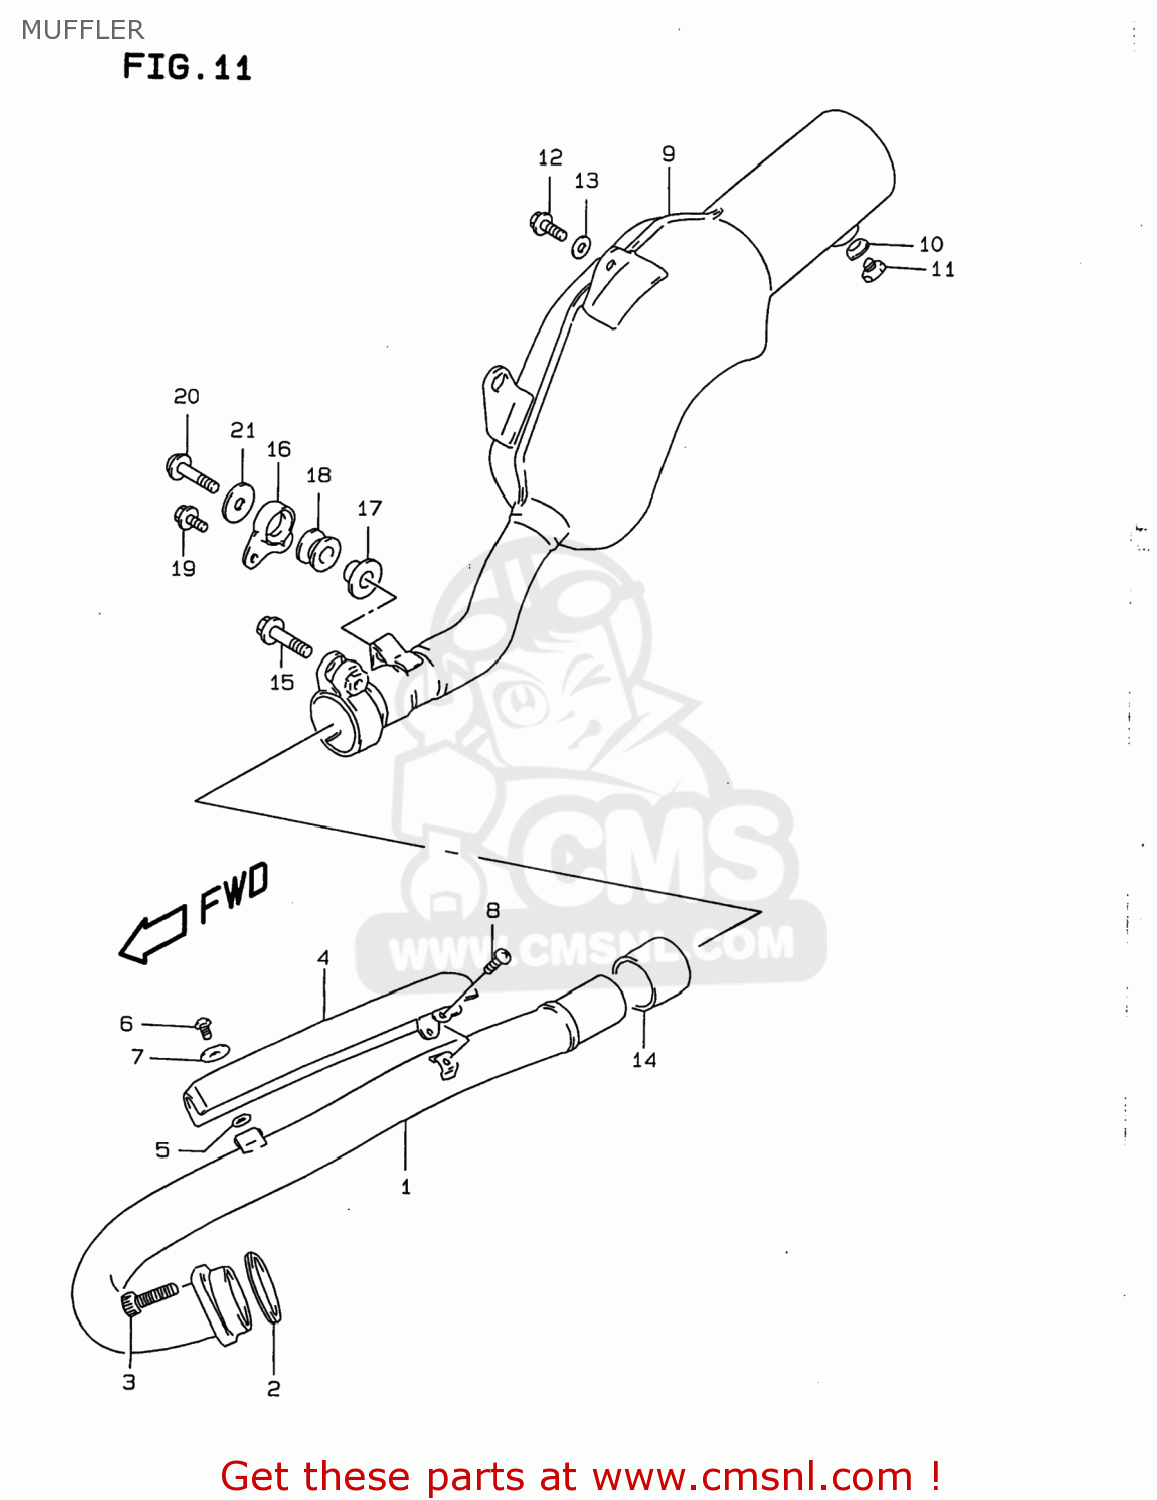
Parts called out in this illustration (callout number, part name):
1	PIPE,EXHAUST
2	GASKET,EXHAUST PIPE (NAS)
3	BOLT
4	COVER,EXHAUST PIPE
5	GASKET(5.8X13X1.4) (NAS)
6	SCREW(6X10)
7	WASHER(6.5X18X1)
8	SCREW
9	BODY,MUFFLER
10	GASKET(12.1X16.2X3.7) (NAS)
11	PLUG(12X9)
12	BOLT(8X20)
13	WASHER (8.5X19X2.3)
14	CONNECTOR,MUFFLER
15	BOLT
16	DAMPER,MUFFLER SUPPORT JOINT
17	SPACER(8.6X12X17.5)
18	CUSHION
19	BOLT 6X12
20	BOLT(8X30)
21	WASHER(8.5X28X1.6)
